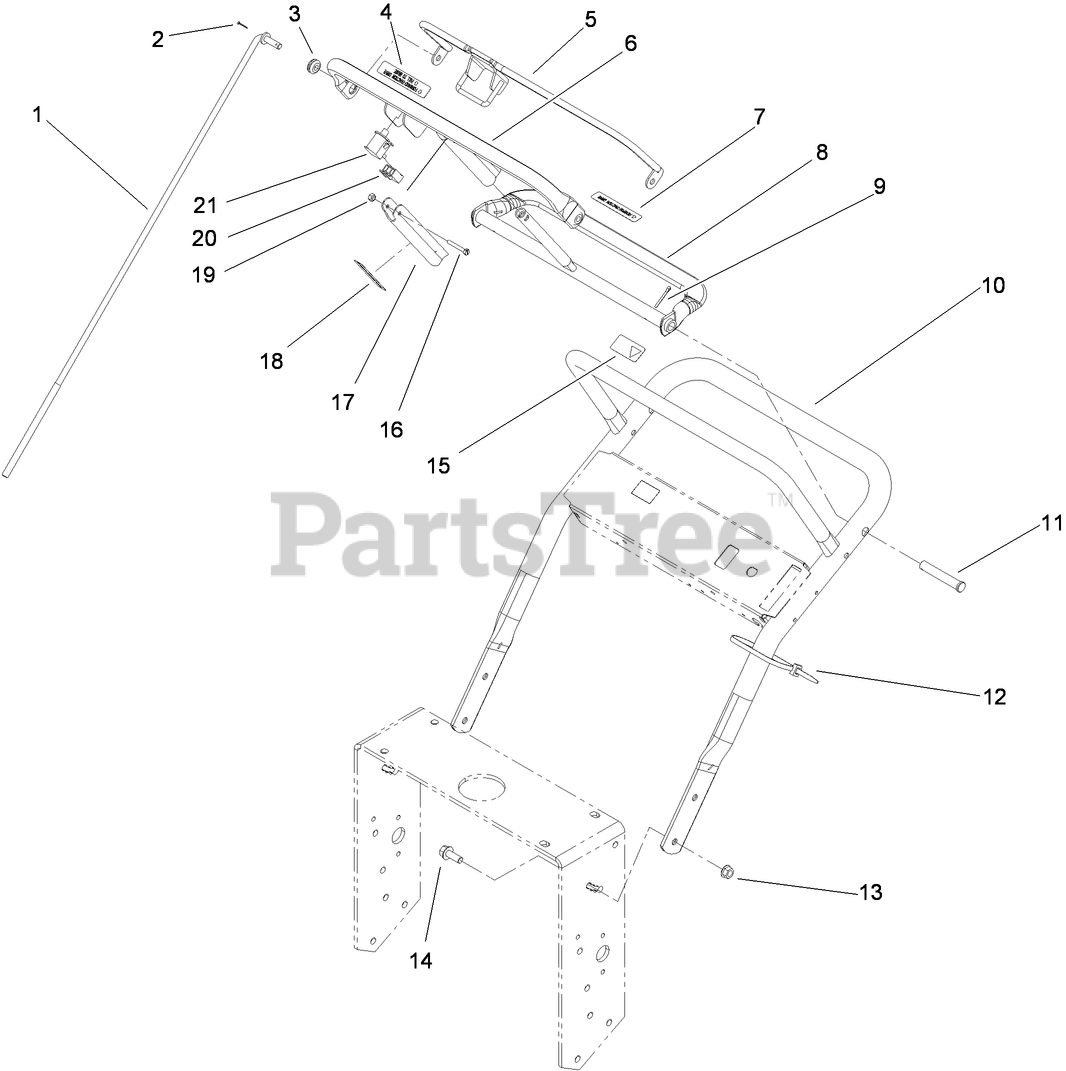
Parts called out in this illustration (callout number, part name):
1	ROD-CONTROL
2	PIN-COTTER
3	GROMMET-RUBBER
4	DECAL-BAR, CONTROL
6	BAR-CONTROL
7	DECAL-REVERSE
8	PIVOT-CONTROL
9	PIN-COTTER
10	Upper Handle ASM
11	PIN-CLEVIS
12	TIE-CABLE
13	NUT-HF
14	SCREW-HHF
15	DECAL-PROTECTION, EAR
16	SCREW-SHH
17	LEVER-BRAKE, PARKING
18	DECAL-LEVER, PARKING
19	NUT-LOCK, NI
20	CONNECTOR-BODY
21	SWITCH-BAIL
